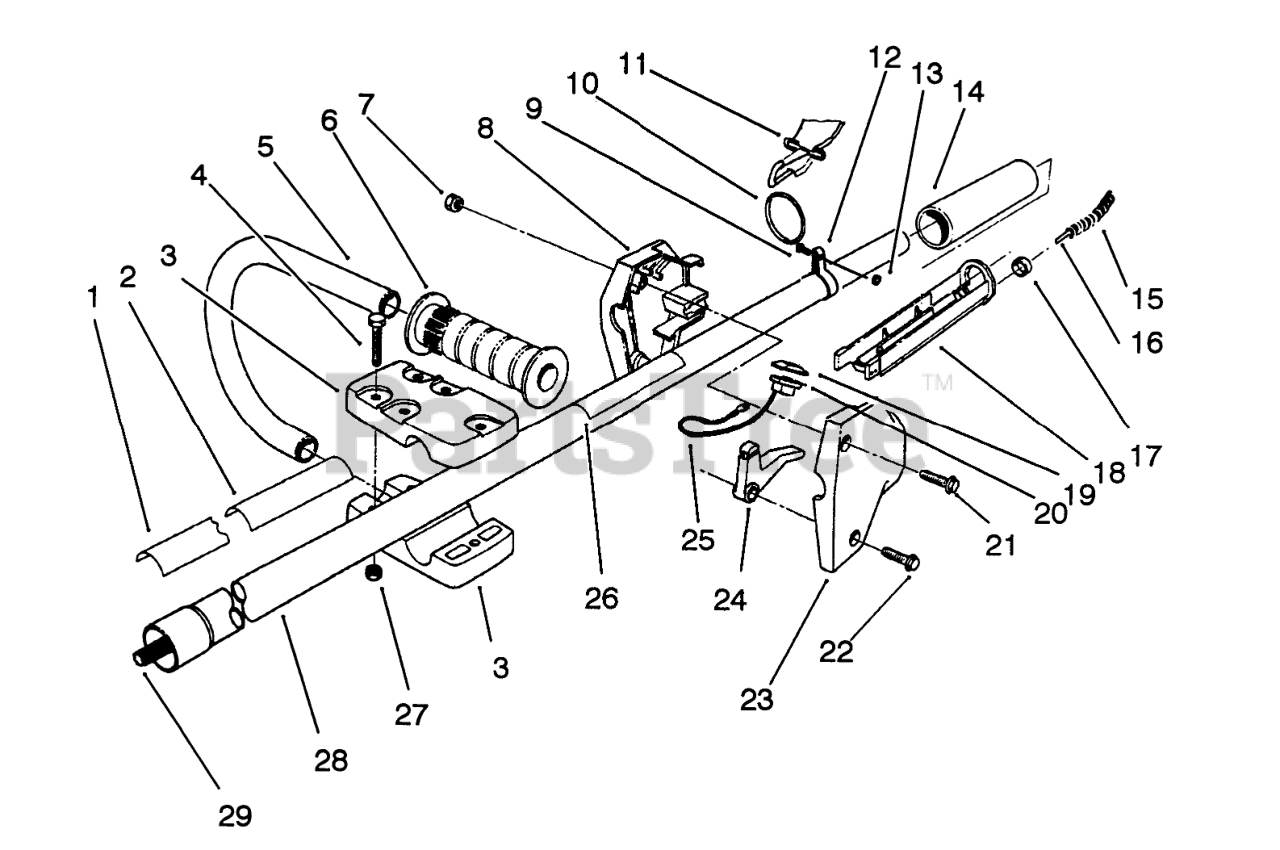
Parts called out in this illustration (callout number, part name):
1	DECAL - TC3500
2	DECAL-DANGER (JAPAN)
3	CLAMP
4	SCREW-HH
5	J HANDLE TUBE
6	LH GRIP
7	NUT-LOCK, NI
8	RH HOUSING
9	SCREW-SRH
10	RING-HARNESS
11	Harness-Shoulder
12	HARNESS CLAMP
13	NUT-LOCK, NI
14	GRIP - RUBBER
15	CABLE COVER
16	THROTTLE CABLE
17	RING FITTING
18	TROUGH 1"
19	SWITCH COVER
20	SWITCH
22	SCREW-SHOULDER
23	LH HOUSING
24	THROTTLE LEVER
25	WIRE ASM
26	DECAL-INSTRUCTION
27	NUT-LOCK, NI
28	TUBE ASSEMBLY
29	SPLINE SHAFT
